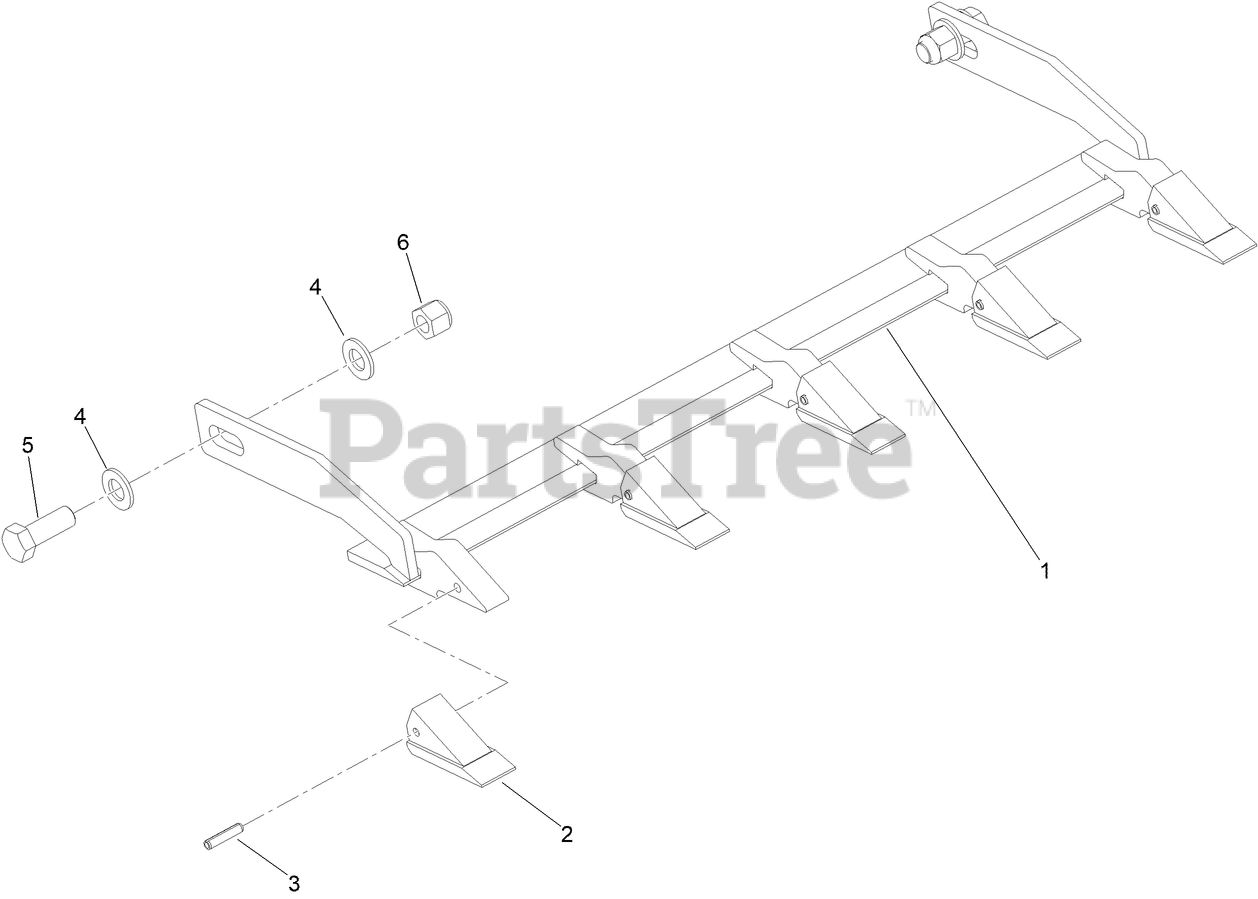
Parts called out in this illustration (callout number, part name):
1	NARROW TOOTH BAR ASM
2	TOOTH-BUCKET
3	PIN-ROLL
4	WASHER-FLAT
5	SCREW-HH
6	NUT-LOCK, NI
